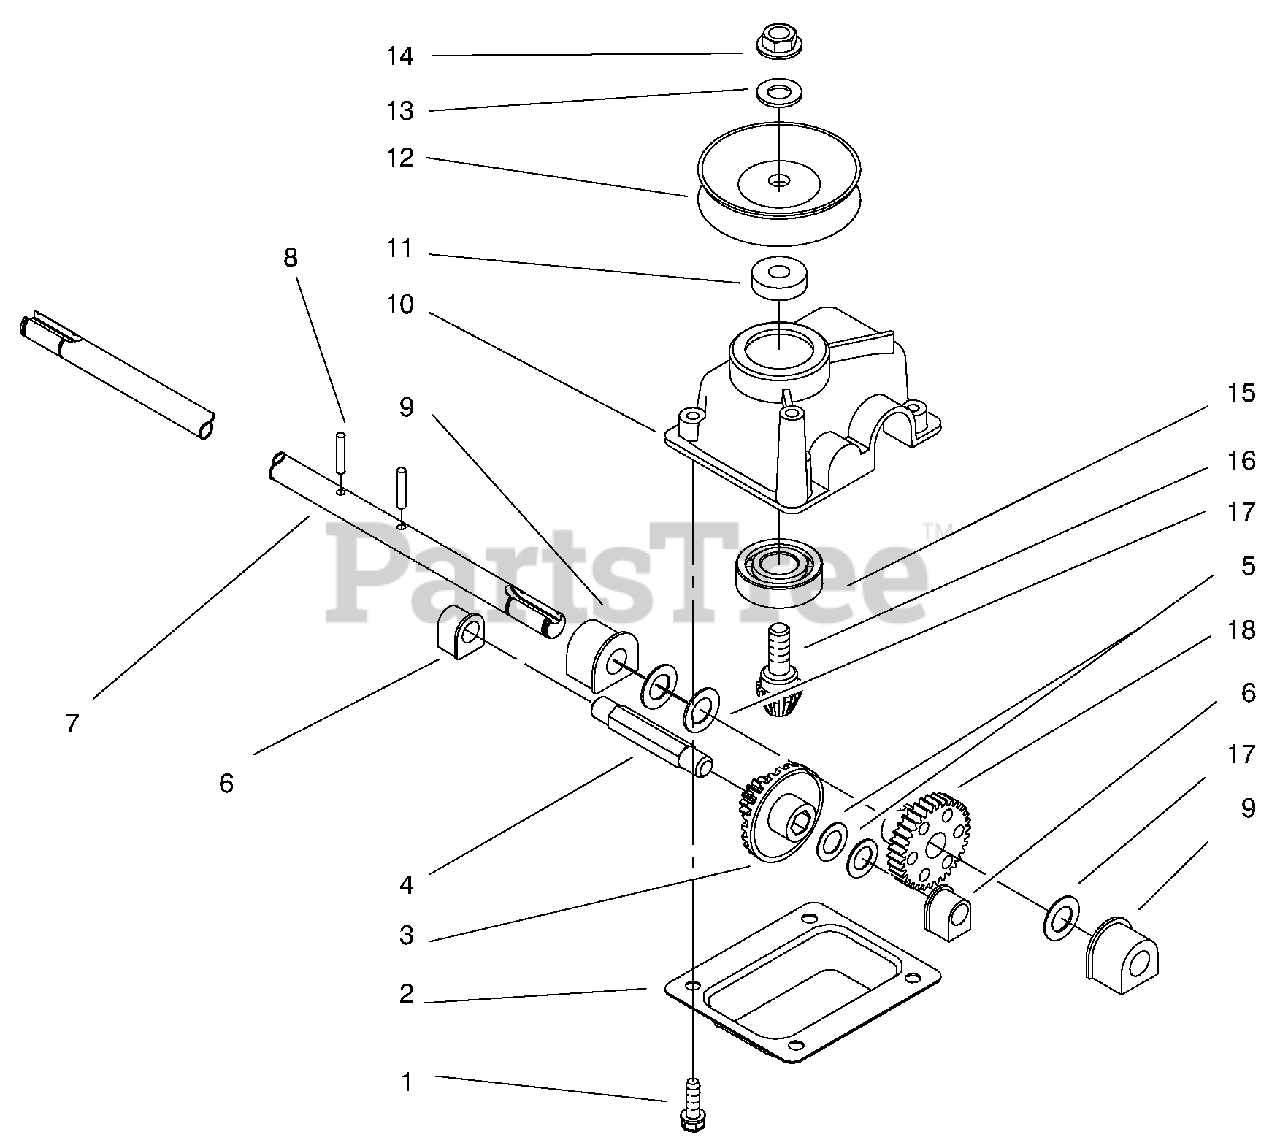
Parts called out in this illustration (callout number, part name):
1	Screw-Taptite
1	Gear Case Ass'y Complete
2	Cover-Gear Case
3	Pinion-15 Tooth
4	Shaft-Intermediate
7	Shaft-Output
8	Pin-Groove
9	Bushing-Output
10	Cover-Gear Case
12	Pulley-Half
15	Bearing-Ball
16	Gear-Bevel Pinion
17	Washer-Thrust
18	Gear 34 Tooth
